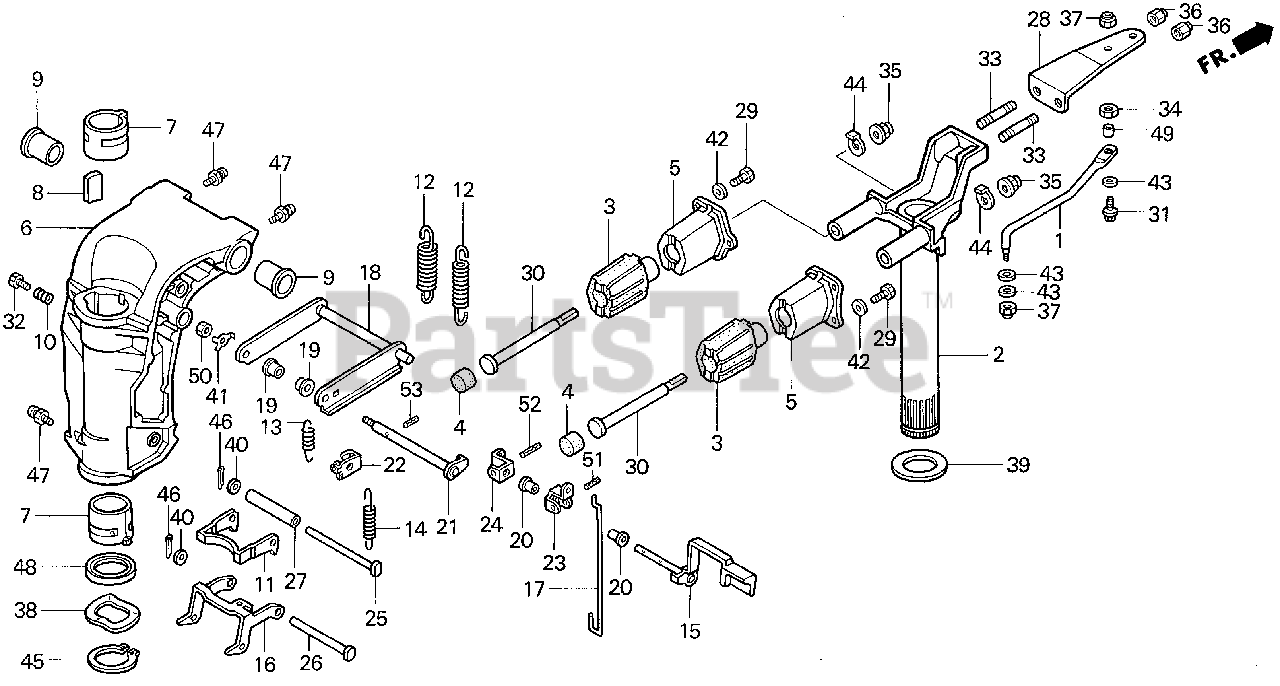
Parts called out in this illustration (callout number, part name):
2	FRAME, MOUNTING *NH282MU* (OYSTER SILVER METALLIC-U)
3	RUBBER, MOUNTING (UPPER)
4	RUBBER, MOUNTING (UPPER) (B)
5	HOLDER, MOUNTING (UPPER) *NH282MU* (OYSTER SILVER METALLIC-U)
6	CASE, SWIVEL *NH282MU* (OYSTER SILVER METALLIC-U)
7	LINER, SWIVEL CASE
8	BLOCK, FRICTION
9	BUSH, SWIVEL CASE
10	SPRING, FRICTION ADJUSTING
11	HOOK, REVERSE LOCK
12	SPRING, REVERSE LOCK
13	SPRING, TILT LEVER
14	SPRING, TILT LINK
15	LEVER, TILT
16	ARM, REVERSE LOCK
17	ROD, RELEASE SWIVEL CASE
18	ARM, TILT
19	BUSH, TILT LEVER
20	BUSH, TILT LEVER
21	SHAFT, TILT
22	BRACKET, TILT SHAFT
23	BRACKET, RELEASE ROD
24	BRACKET, TILT LEVER
25	SHAFT, REVERSE LOCK (A)
26	SHAFT, REVERSE LOCK (B)
27	COLLAR, REVERSE LOCK
29	BOLT, HEX. (6X18)
30	BOLT, SPECIAL (10X130)
32	BOLT, SPECIAL (8X20)
33	BOLT, STUD (10X28)
35	NUT, FLANGE (10MM)
38	WASHER, WAVE (40MM)
39	WASHER, THRUST (34MM)
40	WASHER, PLAIN (6MM)
41	WASHER, LOCK
42	WASHER, PLAIN (6MM)
44	WASHER, SPECIAL
45	CIRCLIP (OUTER) (39MM)
46	PIN, SPLIT (2.0)
47	NIPPLE, GREASE
48	OIL SEAL (39.5X52X6)
50	NUT, HEX. (6MM)
51	PIN, SPRING (2.5X22)
51	PIN, SPRING (3.0X22)
52	PIN, SPRING (2.5X25)
52	PIN, SPRING (3.0X25)
53	PIN, SPRING (3X25)
53	PIN, SPRING (3.0X25)
